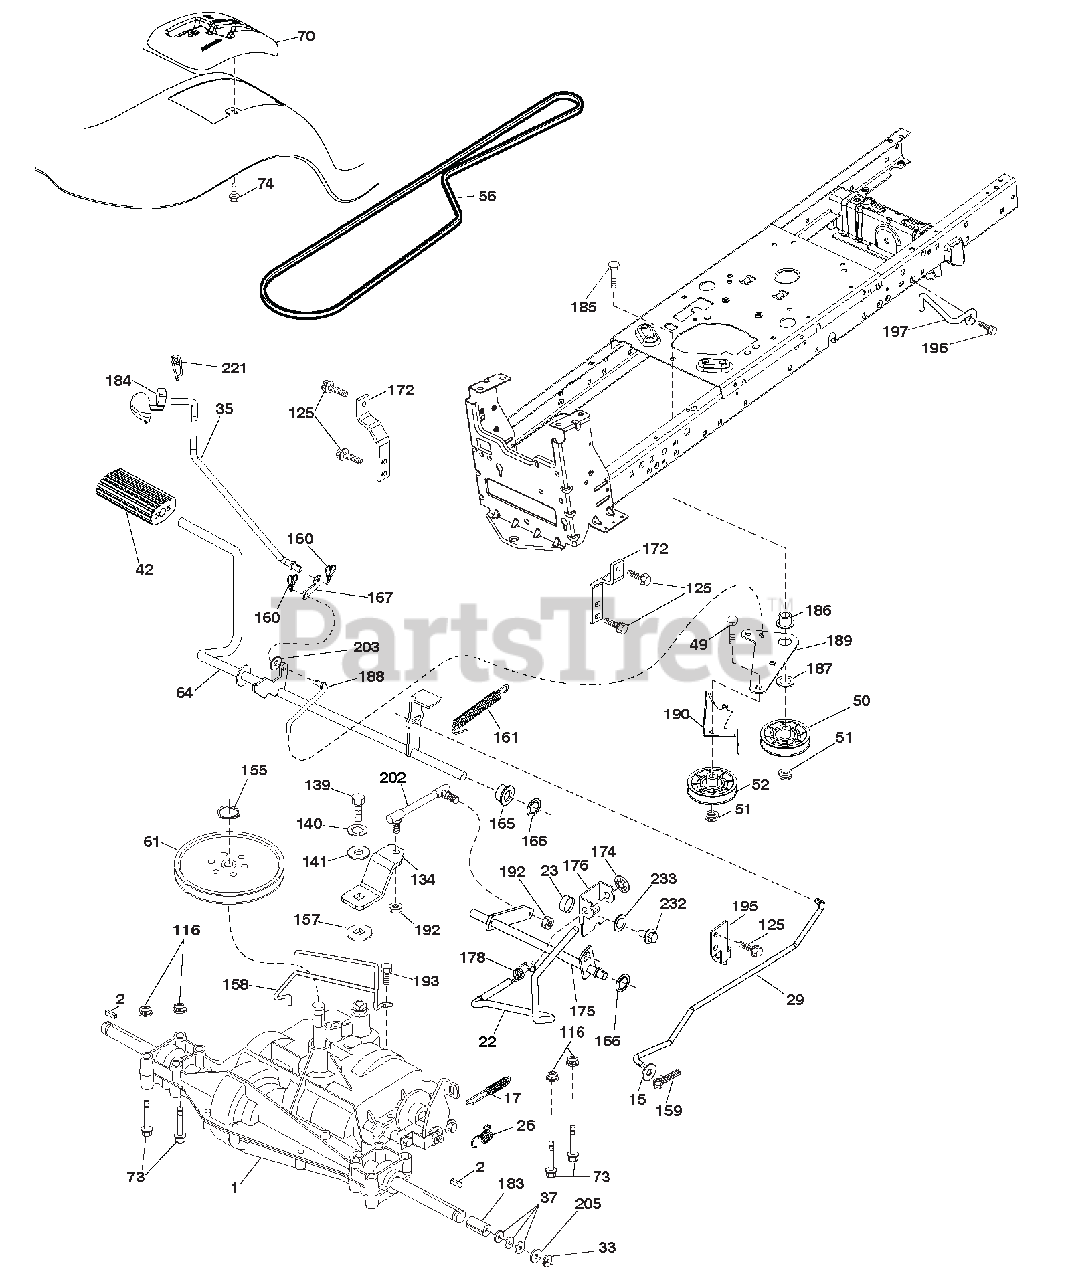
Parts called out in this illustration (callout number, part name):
2	KEY.SQUARE.2.0 X .1845/.1865
15	WASHER.13/32 X 13/16 X 16 GA.
17	SPRING.BRAKE.PEERLESS/D6800.TX
22	ROD.SHIFT.FENDER.TLT.2006
26	SPRING.BRAKE.RTN.GR DR.TEX.006
29	ROD.BRAKE.PEERLESS/D6800
33	E-RING.#5133-75
35	ROD, BRAKE, PARK
37	WASHER.25/32 X 1 1/4 X 16 GA.
42	COVER PEDAL BLK ROUND
49	BOLT.RDHD.3/8-16UNCX1-3/4.GR5
50	IDLER.FLAT.910"OFFSET
51	Nut, Hex, Flangelock 3/8-16
52	IDLER.V-GROOVE.910"OFFSET
56	V-BELT.DRV.97.40"PMST/DANA
61	PULLEY.TRANSAXLE.18/20"TIRES
64	SHAFT ASM.PEDAL.BRAKE CONTROL
70	CONSOLE SHIFT
73	BOLT 5/16-18 X 2 1/2 G.5
74	SCREW.HEX.WSH.HI-LO.1/4X1/2UNC
116	Nut, Lock Hex Flange 5/16-18 u
125	SCREW.5/16-18X3/4.SMGML.TAP/BL
134	ASM SHIFT
139	BOLT.1/4-28 UNF.GR8.W/PATCH
140	Washer, Lock 1/4
141	WASHER.9/32 X 3/4 X 10 GA.
155	Ring, Retainer
157	WASHER.PLATE.SHF..388 SQ.HOLE
158	KEEPER.T/A.PMS/D4360/D680.1820
159	PIN.COTTER.1/8 X 3/4.CAD.
160	RETAINER.CLIP(M).DIA.290
161	SPRING.RETURN.CLUTCH.6.75
165	BUSHING.SHAFT.BRAKE.HAND CONTR
166	NUT PUSH .625
167	LATCH.BRAKE.PARKING
172	STRAP.TRQ.LH.GEAR DRIVE.LT.TEX
174	NUT.PUSH..500
175	SHAFT ASM. SHIFT GEAR DRIVE
176	ARM.CLEVIS.ROD.SHIFT
178	SPRING.SHIFT.GT.2006
183	SPACER.AXLE.HYDRO/PEERLES
184	HANDLE PARKING BRAKE
185	BOLT.RDHD.3/8-16UNC X2-3/4 GR5
186	SPACER.RETAINER
187	WASHER.13/32 X 2 X 10 GA.
188	LINK.CLUTCH.GROUND DRIVE
189	BELLCRANK.GROUNDRIVE.NSTG/NSTL
190	KEEPER.BELLCRANK.DRIVE.GROUND
192	NUT.LOCK.CENTER.1/4-28 FNTHD.
193	SCREW.5/16-18X3/4.SMGML.TAP/R
195	BRACKET.ROD.BRK.PEERLESS/D6800
196	SCREW.3/8-16X1.SMGML.TAP/R.BLK
197	LINK.CLUTCH.ANTI-ROTATIN.1"CRK
203	Washer 11/32 x 11/16 x 16 Ga.
205	WASHER.25/32 X 1-5/8 X 16GA.
221	RETAINER.SPRING.CLIP.HANDLE
232	BOLT.FIN HEX.7/16-14X1 GR5
233	WASHER.SERRATED
